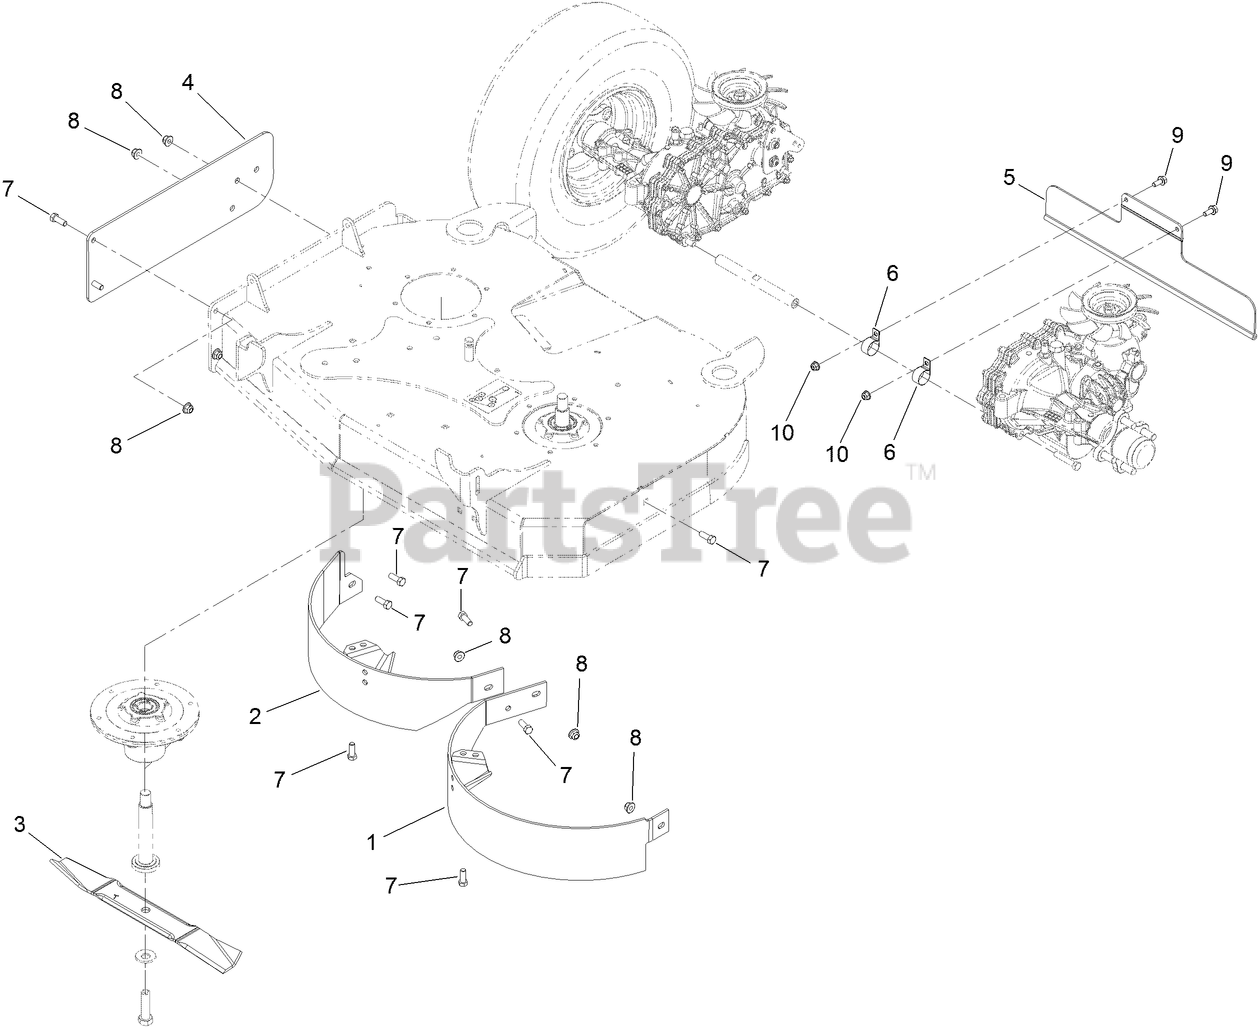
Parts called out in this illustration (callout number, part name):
1	LH BAFFLE ASM
2	RH BAFFLE ASM
3	BLADE - MULCH, 18.00 IN
4	PLATE-DISCHARGE, COVER
5	SHIELD-TRAILING
6	CLAMP-R
7	SCREW-HH
8	NUT-HF, NI
9	SCREW-HHF
10	NUT-HF, NI
